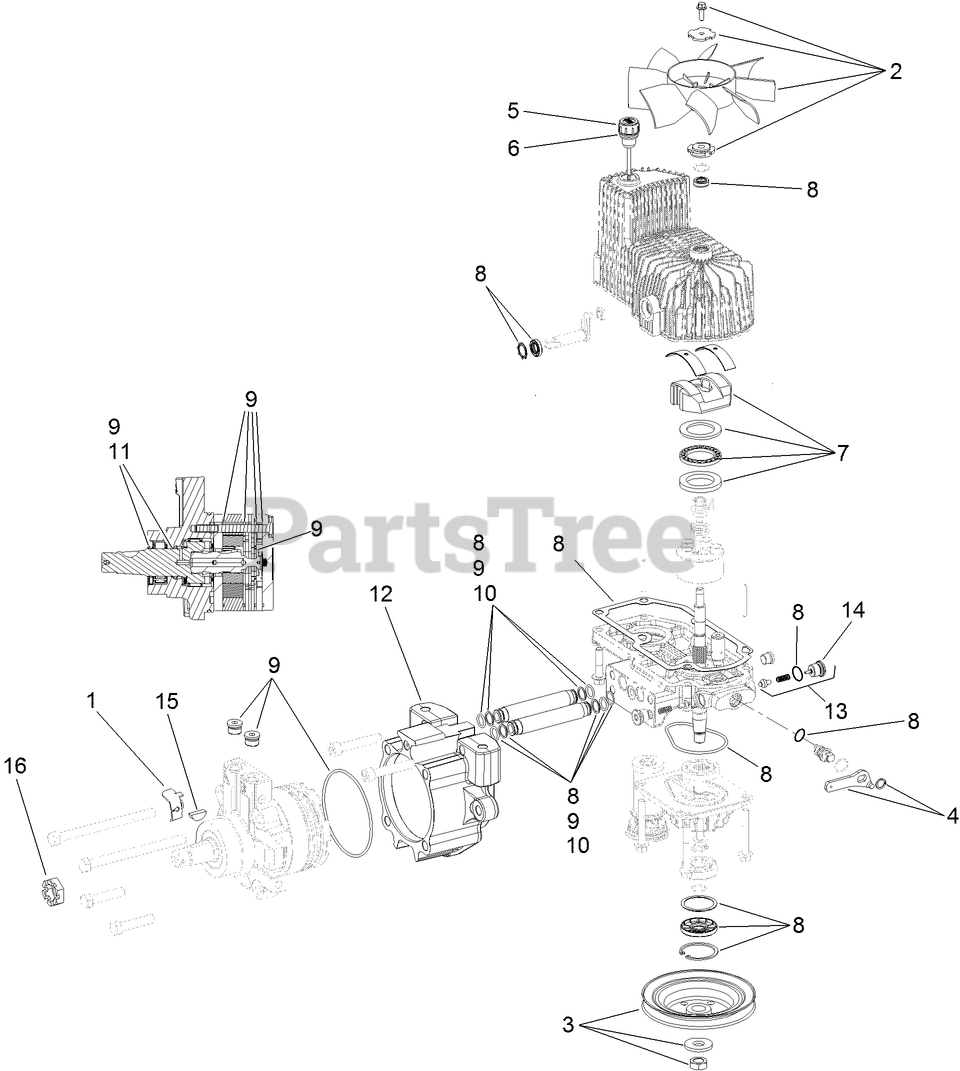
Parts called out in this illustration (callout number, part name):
1	BRACKET-ANCHOR, CABLE
2	FAN KIT
3	PULLEY KIT
4	HANDLE-BYPASS VALVE, HYDRO
5	DIPSTICK-HYDRO W/GASKET
6	GASKET-DIPSTICK, HYDRO
7	SWASH BLOCK KIT
8	PUMP SEAL KIT
9	MOTOR SEAL KIT
10	TUBE SEAL KIT
11	OUTPUT SHAFT SEAL KIT
12	CUP-NOSE
13	CHECK VALVE ASM
14	PLUG-CHECK (W/O-RING)
15	KEY-WOODRUFF
16	NUT-HH
